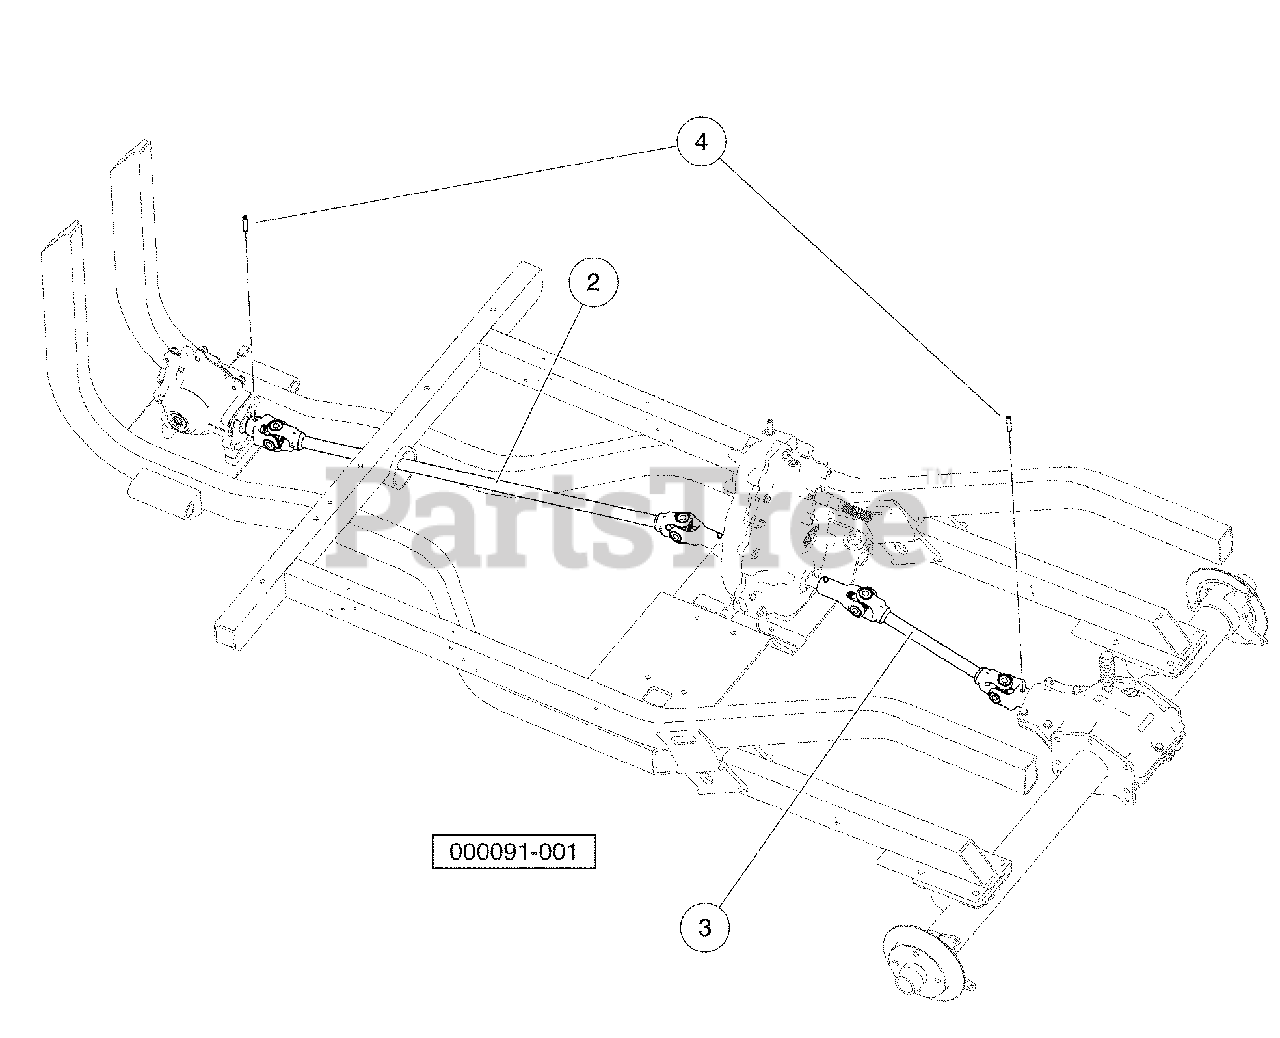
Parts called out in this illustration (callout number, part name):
1	Inst, Prop Shafts, Awd
2	Prop Shaft, Front
3	Prop Shaft, Rear
4	Pin, Spring, 5/16 X 1-1/2 Hd
